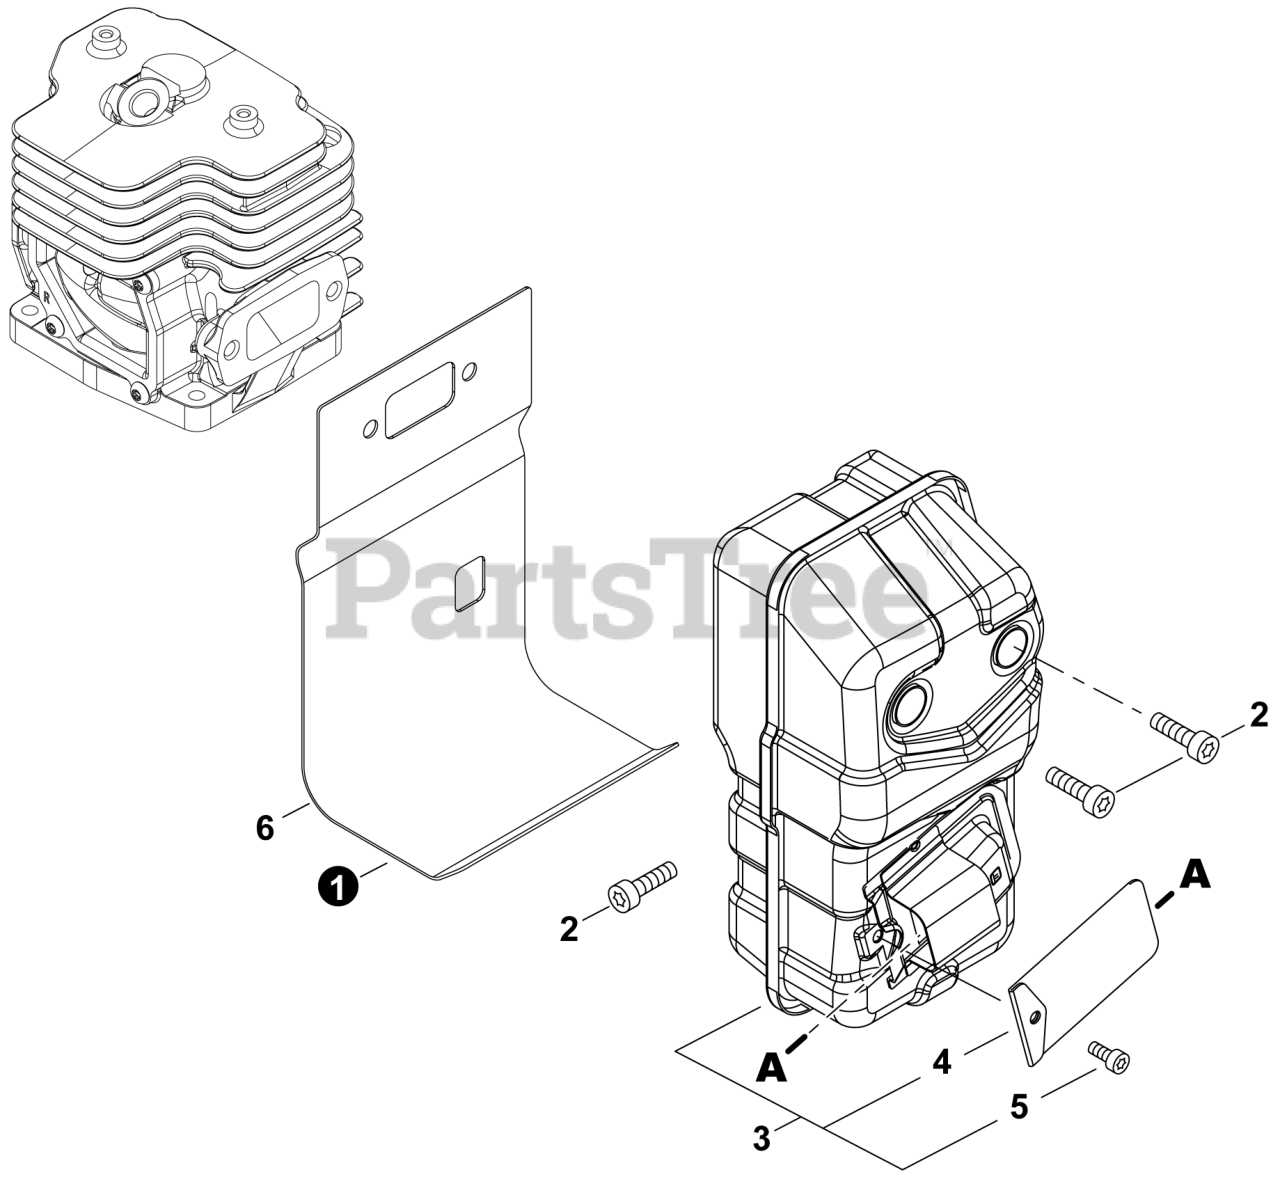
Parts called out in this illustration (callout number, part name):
1	HEAT SHIELD, EXHAUST
2	BOLT, TORX 6x20
3	MUFFLER ASSY
4	SCREEN, SPARK ARRESTER
5	BOLT, TORX 4x8
6	GASKET KIT: ENGINE, INTAKE, EXHAUST
